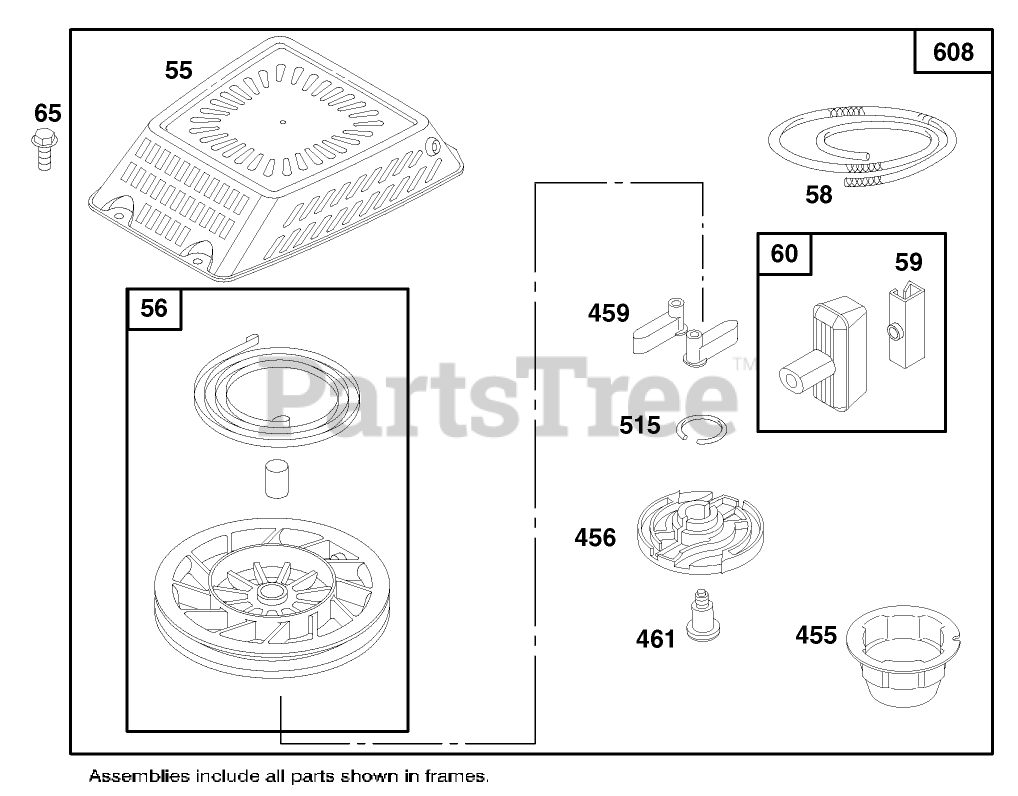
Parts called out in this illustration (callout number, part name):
56	PULLEY-STARTER, REWIND
58	ROPE-STARTER
59	INSERT-HANDLE, REWIND
455	CUP - STARTER
456	RETAINER-STARTER, REWIND
459	PAWL-STARTER
515	SPRING-TORSION
608	BRIGGS #498146
